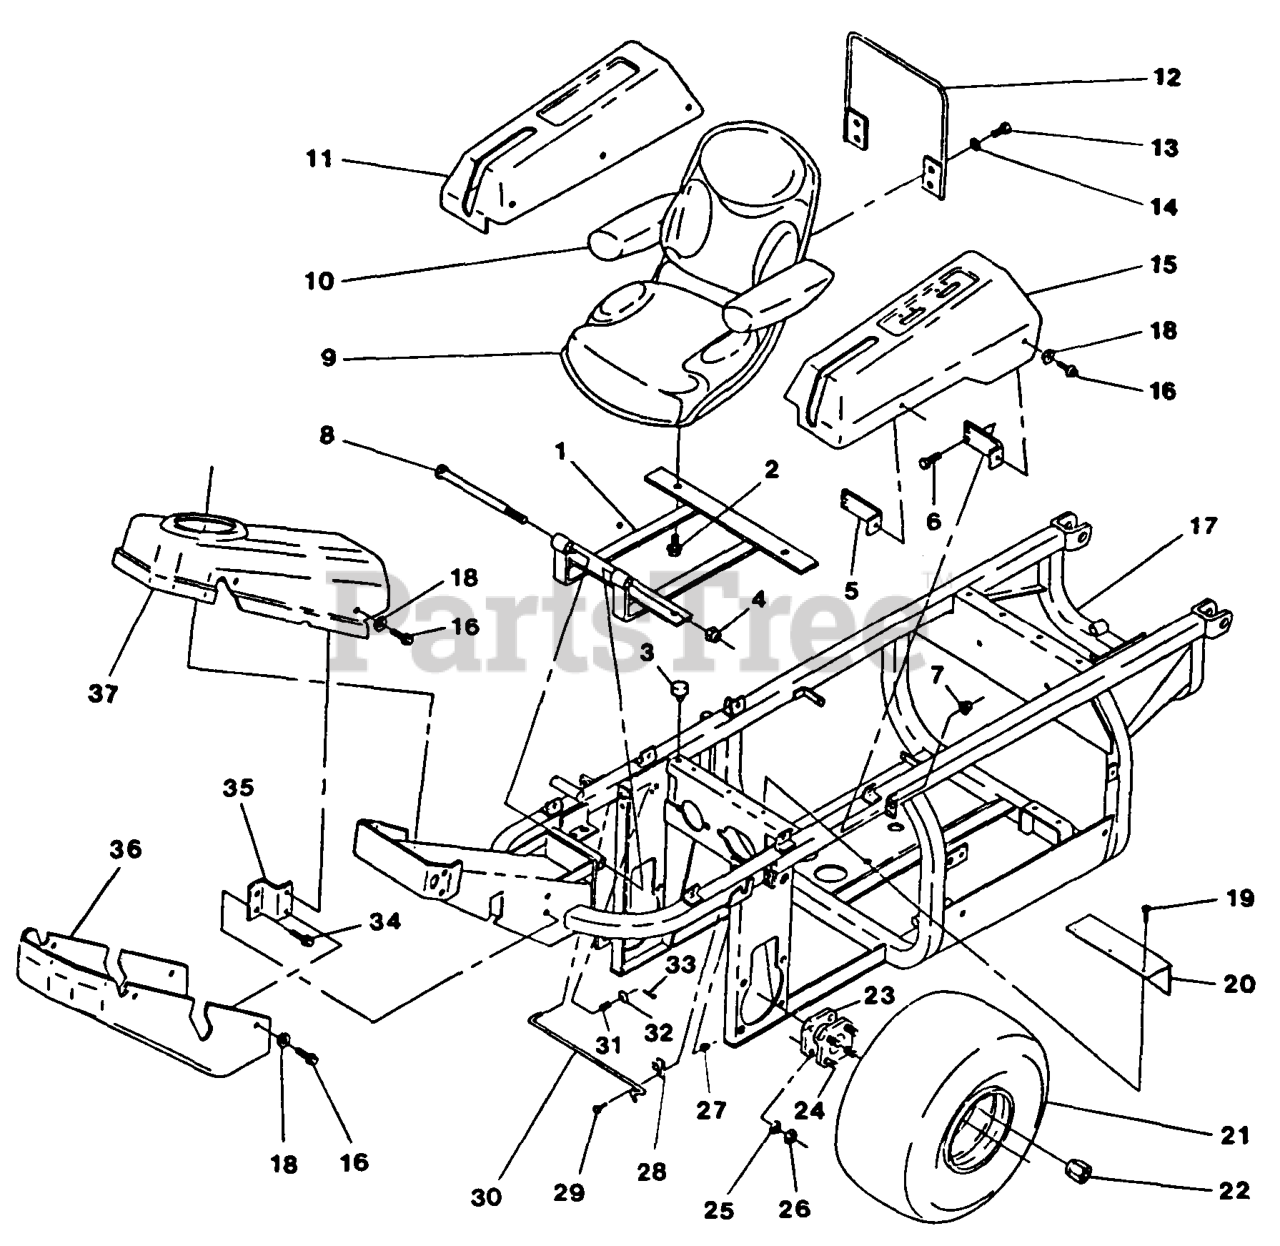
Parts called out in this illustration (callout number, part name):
11	FENDER,RH RANGER
15	FENDER,LH RANGER
24	BOLT,HUB
28	CLIP,SEAT HOLDUP ROD
30	ROD,SEAT HOLDUP
31	SPRNG,ST HOLDUP ROD
36	CONSOLE,STEERING BOTTOM
37	CONSOLE,STEERING TOP
